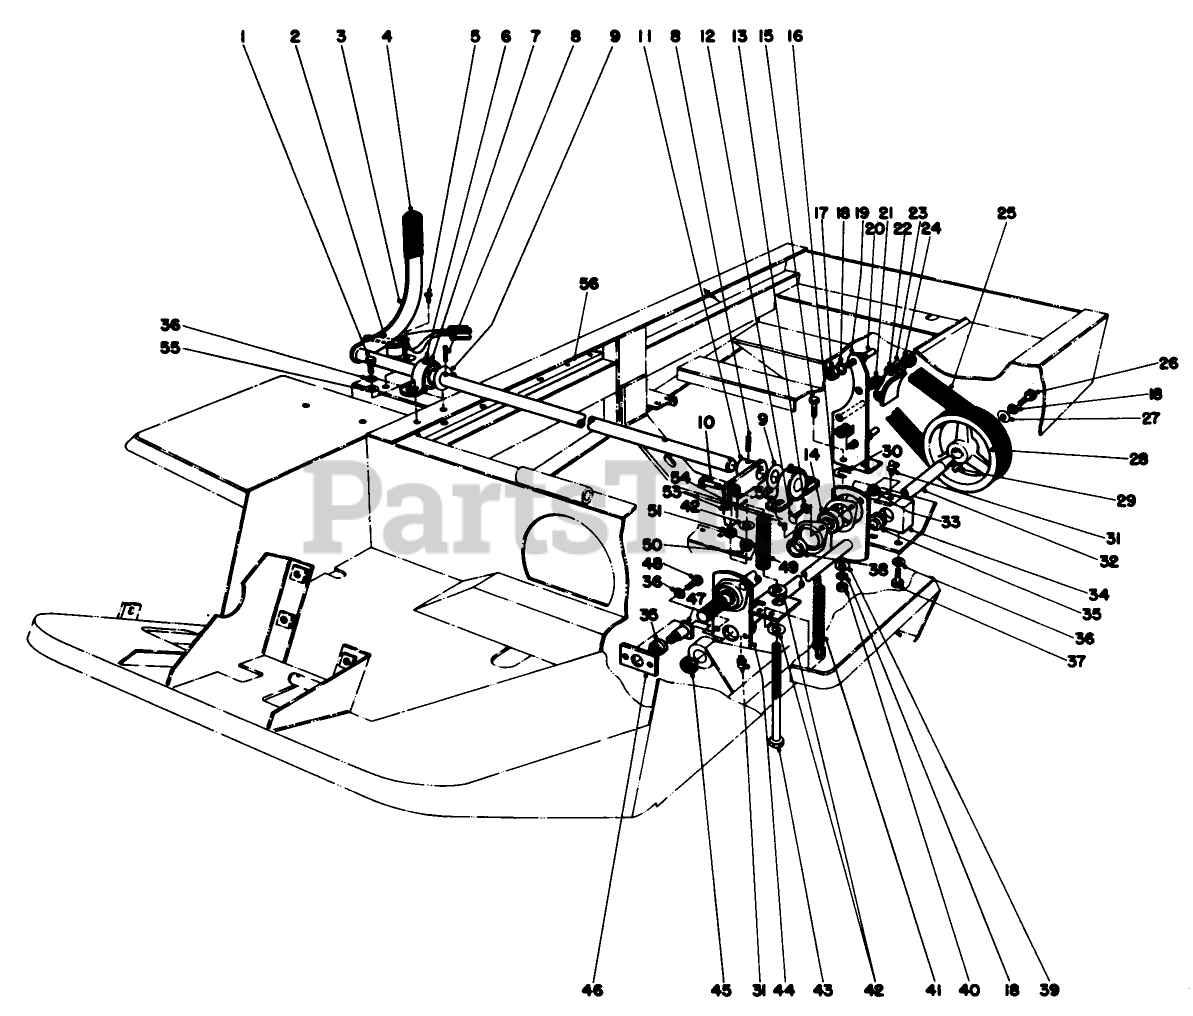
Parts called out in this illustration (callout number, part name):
1	Bolt
3	P.T.O. Lever
4	GRIP-HANDLE
6	FITTING-GREASE
7	BEARING
8	PIN-SPRING
9	THRUST WASHER
10	Clevis Pin
11	ENGAGE ARM WA
12	SCREW-CARR
13	Lockwasher
14	BEARING
15	SCREW-HH
16	FLANGE
17	NUT-JAM
18	WASHER-LOCK
19	PTO BRAKE BRKT WA *BO
21	COMP SPRING *O
23	WASHER-FLAT
24	NUT-HEX
26	SCREW-HH
27	WASHER-FLAT
28	P.T.O. Pulley
29	KEY-WOODRUFF
30	SPECIAL WASHER
31	Fitting-Grease
32	Shaft P.T.O.
33	NUT-HEX
35	BEARING
36	WASHER-LOCK
37	SCREW-HH
38	COLLAR-LOCK, BEARING
39	WASHER-FLAT
40	NUT-HEX
42	Washer
43	SCREW-ADJUSTING
45	NUT-LOCK, NI
46	BRG RETAINER
47	BEARING STUD
48	SCREW-HH
50	NUT-HEX
51	NUT-HJ
52	SCREW-SET, HSH
54	PIN-COTTER
55	WASHER-FLAT
